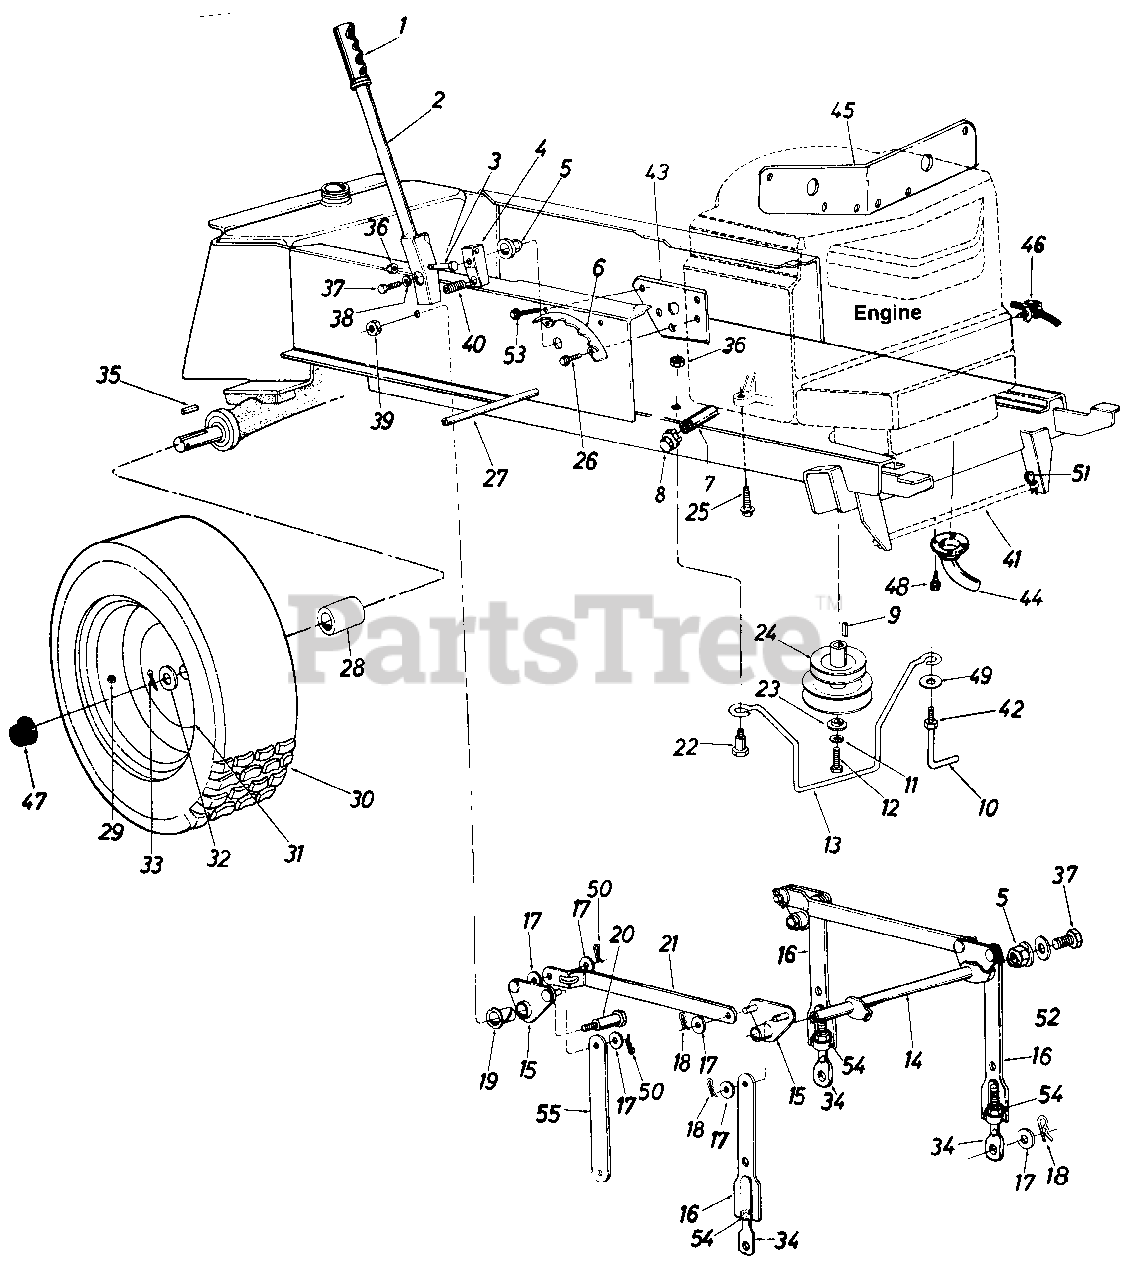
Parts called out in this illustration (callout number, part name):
1	Grip
2	Lift Handle Ass'y.
3	Hex Bolt 5/16-18 x 1.5" Lg.
4	Lift Shatt Drive
5	Plastic Hex Brg. 5/8" I.D.
8	Pipe Cap 3/8-18 Npt.
9	Sq. Key 1/4" x 1/4" x 1.50" Lg.
10	Belt Guard Lock Pin
11	L-Wash. 7/16" I.D.
12	Hex Scr. 7/16-20 x 1.50" Lg.
13	Belt Guard
14	Lift Shaft Ass'y.
15	Lift Pivot Brkt. Ass'y.
17	Fl-Wash. 1/2" I.D. x 1.00" O.D. x .090
18	IHairpin Cotter
19	Nyliner 5/8" I.D. x .88" Lg.
20	Shld. Bolt 5/8" Dia. x .96" Lg. 3/8-16
23	Flat Wash. .44" I.D. x 1.25" O.D. x .17
24	Two-Step Engine Pulley 4.75" & 5.56
25	Hex Wash. Hd. Scr. 3/8-16 x 1.25" Lg.
26	Hex Thd. Rolling Scr. 5/16-24 x .50" Lg.
27	Running Board Rod
28	Spacer 1.0" I.D. x 1.25" O.D, x2.12" Lg.
29	Air Valve
30	Rear Wheel Ass'y. Comp.
33	Cotter Pin 3/16" Dia. x 1.50" Lg.
34	Eye Bolt Adj. Link 1/2-13 Thd.
35	Sq. Key 1/4 x 3.0"
36	Hex Cent. L-Nut 5/16-18 Thd.
37	Hex Scr. 5/16-24 x .62" Lg.
38	L-Wash. 5/16" I.D.
39	Hex Top L-Nut 3/8-16 Thd.
40	Compression Spring
41	Deck Connecting Rod
42	Hex Nut 5/16-24 Thd.
45	Heat Shield
46	Mounting Clamp
48	Hex Wash. Hd. AB-Tap Scr. #10 x .50" Lg.
49	Bell-Wash..39" l.D.
50	Cotter Pin .09 Dia. x 1.0" Lg.
51	Int. Cotter Pin
52	Flat Wash. .34" I.D. x 1.12" O.D. x .125
53	Hex Wash. Hd. AB-Tap Scr. 5/16 x .62" Lg.
54	Hex Nut 1/2-13 Thd.
